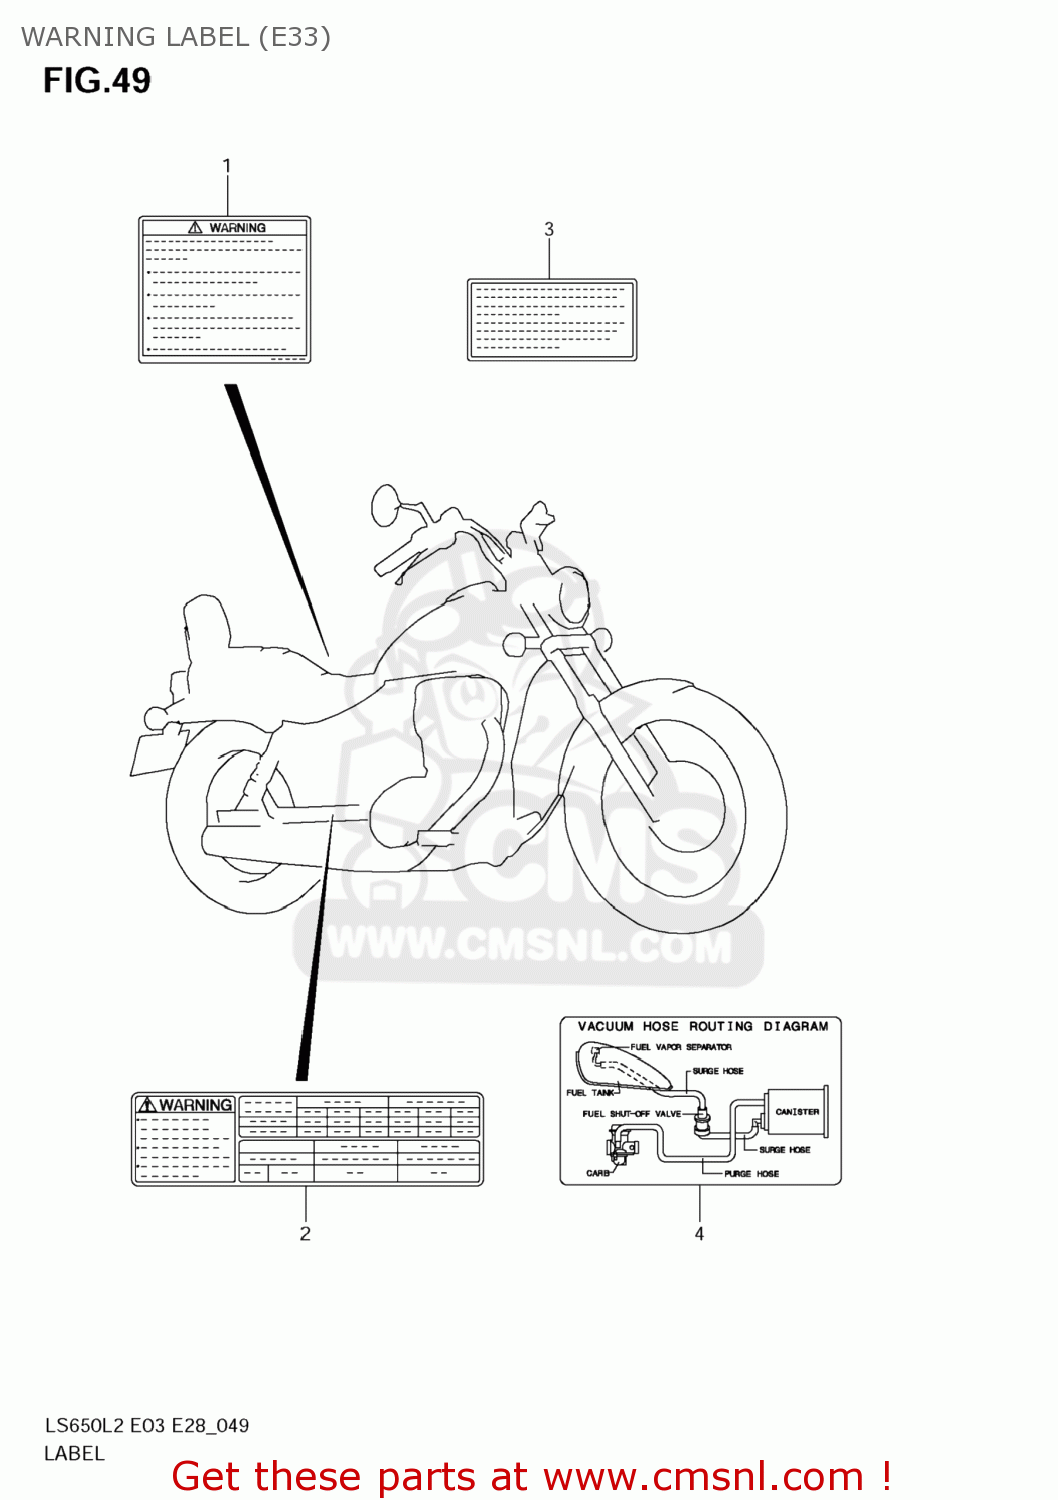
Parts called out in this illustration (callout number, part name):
1	LABEL,GENERAL WARNING
2	LABEL,TIRE INFORMATION
3	LABEL,MANUAL NOTICE
4	LABEL,VACUUM HOSE ROUTING
5	MANUAL,OWNER'S
